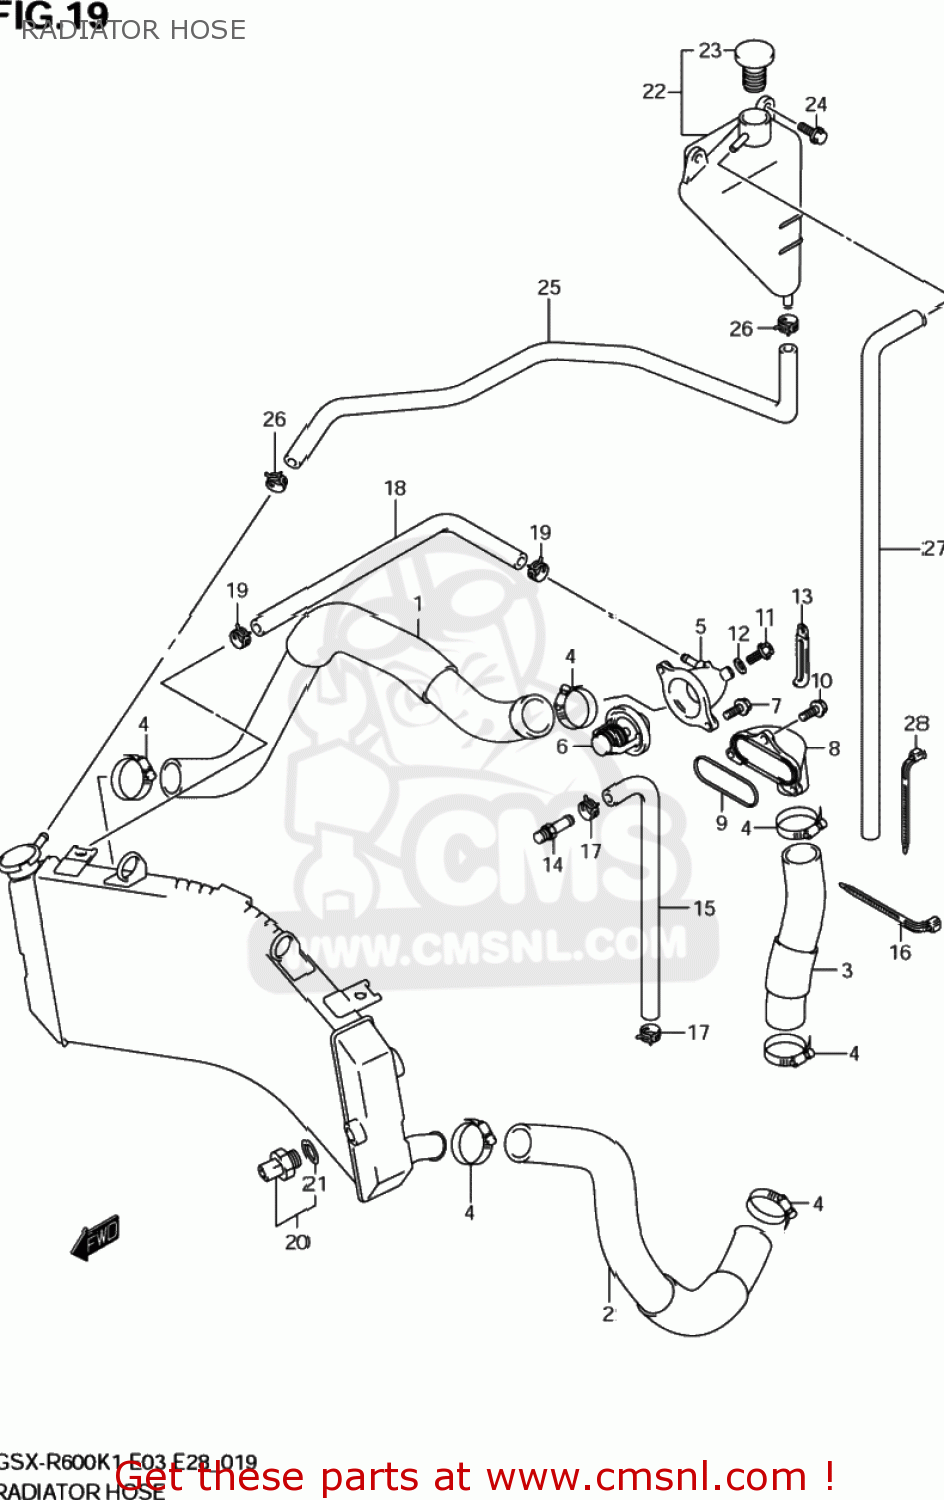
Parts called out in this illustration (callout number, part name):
1	HOSE,RADIATOR INLET
2	HOSE,RADIATOR OUTLET
3	HOSE,CYLINDER
4	CLAMP
5	COVER,THERMOSTAT
6	THERMOSTAT,WATER 82 DEG
7	SCREW
8	CONNECTOR,CYL.
9	O RING,CYL WATER CONNECTOR
10	SCREW
11	UNION BOLT,AIR VENT
12	GASKET(6.4X11.5X0.8) (NAS)
13	CLAMP(L:65)
14	BOLT UNION
15	HOSE,WATER BYPASS
16	CLAMP(L:165)
17	CLAMP
18	HOSE(5X11X600)
19	CLIP
20	SWITCH,RADIATOR FAN
21	O-RING
22	TANK ASSY,RESE
23	CAP,RESERVOIR TANK
24	BOLT
25	HOSE,RESERVOIR TANK INLET
26	CLIP
27	HOSE(5X9X600)
28	CLAMP(L:165)
